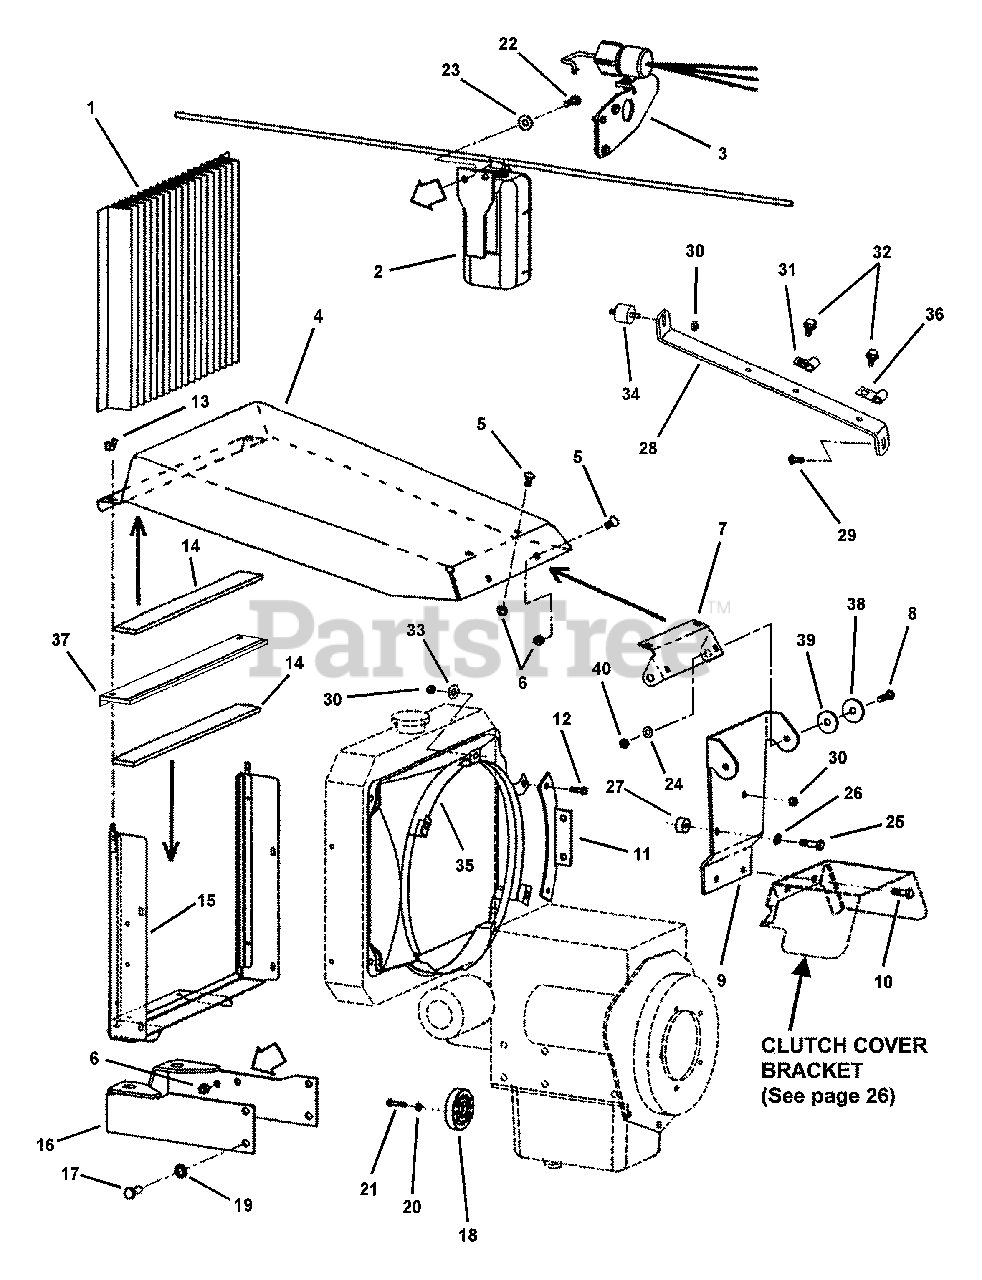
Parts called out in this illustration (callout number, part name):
1	SCREEN, Radiator
3	KIT, Solenoid
4	WELDMENT, Engine Hood
5	BOLT, 5/16-18 x 5/8" Short Neck Carriage, Grade 5
6	NUT, 5/16-18 HEX NYLON LOCK
7	BRACKET, Hood Hinge
8	BOLT, 5/16-18 X 1-1/4 GD5 YZ
9	SUPPORT, Engine Hood
10	BOLT, M8-1.25 X 25MM GD8.8
11	BRACKET, Air Cleaner
12	SCREW, M6-1.00 x 20mm Hex Head Cap
13	WINGNUT, 1/4-20 Locking
14	STRIP, Sponge Rubber
15	WELDMENT, Radiator Screen Support
16	BRACKET, Radiator Support
17	SCREW, M10-1.25 x 25mm Hex head Cap
18	SPACER, Fan
19	WASHER, 7/16 Split Lock
20	WASHER, 1/4" Split Lock
21	SCREW, M6-1.00 x 25mm Hex Head Cap
22	BOLT, 5/16-18 X 1 GD5 YZ
23	WASHER, 3/8" Flat
24	WASHER, 5/16 Flat
25	SCREW, M8-1.25 x 30mm Hex Head Cap
26	WASHER, .32 I.D. Split Lock
27	SPACER, .33 I.D. x .75 O.D. x .459 Long
28	BRACE, Radiator
29	BOLT, 1/4-20 x 3/4" Square Neck Carriage, Grade 5
30	NUT, 1/4-20 Hex Top Lock
31	HARNESS CLIP, 3/8"
32	SCREW, 5/16-18 x 5/8" Hex Washer Face Self-Tap
33	WASHER, 1/4" Flat
34	ISOLATOR, Stud Mount
35	SHROUD, Kubota Diesel Radiator
36	J-CLIP, 3/8"
38	WASHER, .406 x 1.50 Flat
39	FRICTION PAD, Spacer
40	NUT, 5/16-18 Hex Center Lock Jam
